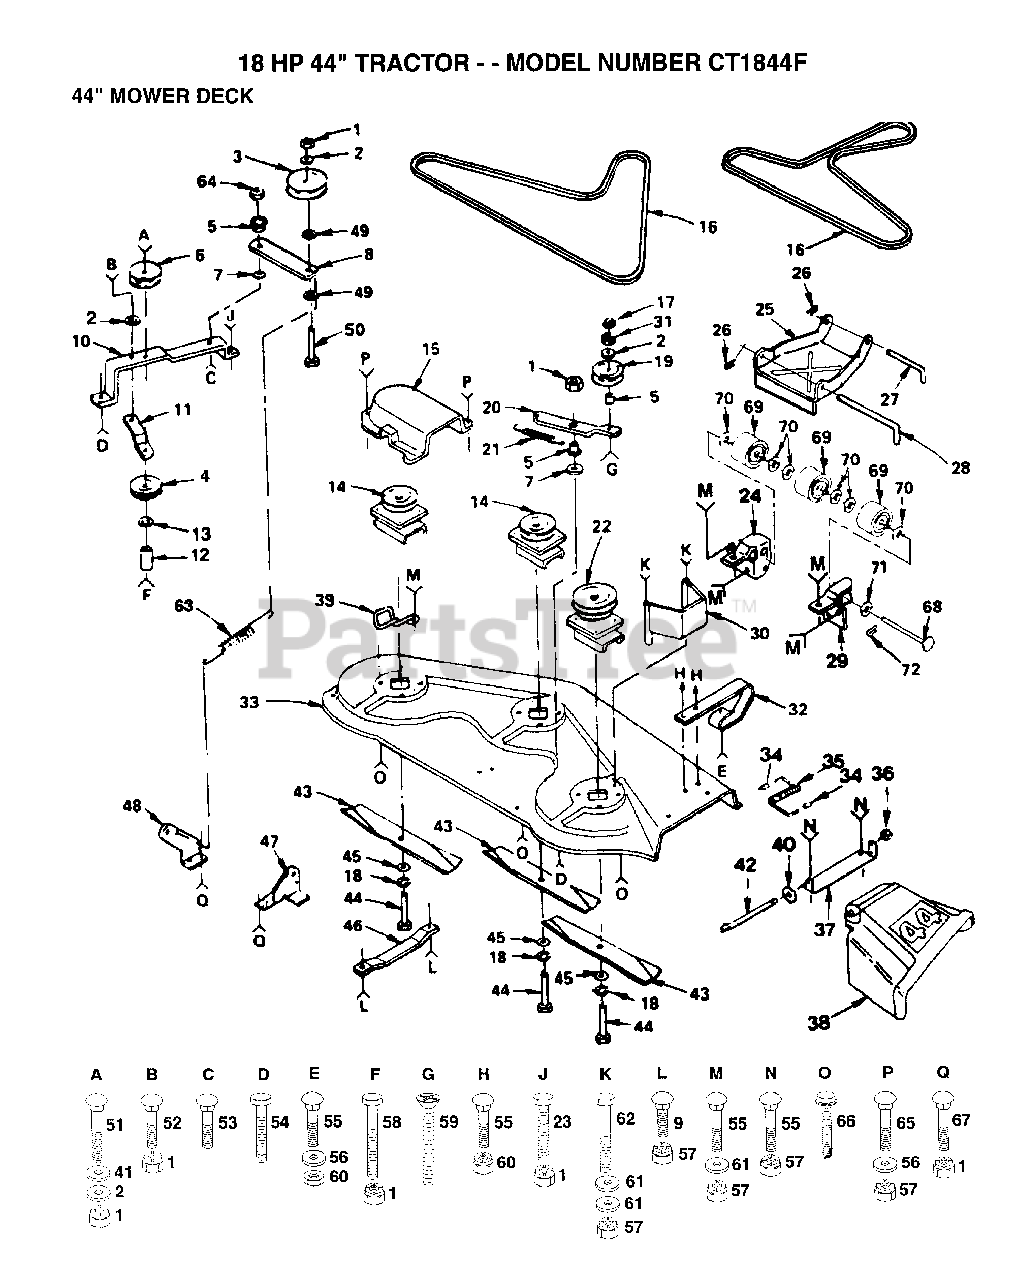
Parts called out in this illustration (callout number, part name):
2	WASHER
3	PULLEY IDLER
4	IDLER-FLAT T
5	SPACER RETAINER
6	IDLER-INSIDE T
7	"WASHER, WEAR LT"
8	ARM IDLER
9	BOLT
10	"SUPPORT YT, BAR"
11	BRACE-IDLER YT
12	SPACER
13	WASHER
15	GUARD YT
16	BELT-V.79.1.MWR
17	NUT.HEX.3/8-16UNC
19	"WASHER, PLAIN LT"
20	ARM-IDLER YT
22	JACKSHAFT
23	BOLT
24	BRACKET LH YTH
25	LINK.PARALLEL
26	SPRING.RETAINER
27	"ROD, FRT. PARAL T"
28	HINGE PIN T
29	BRACKET RH YTH
30	GUARD BELT HYT
31	LOCKWASHER
32	RUNNER.RH
34	CAP-SLEEVE LT
35	SPRING TORSION
36	NUT PUSH M
37	BRKT DEFLECTOR
38	DEFLECTOR SHIELD
39	BELT RETIANER
40	WASHER
41	WASHER
42	ROD-HINGE T
44	BOLT.3/8-24X1-1/2
45	WASHER
46	RUNNER-LH M
47	BRKT SUSP REAR RH
48	BRKT SUSP REAR LH
49	WASHER
50	BOLT
51	BOLT
53	BOLT
55	BOLT
56	WASHER
58	BOLT - HEX 3/8 - 16 X 3
59	SCREW YT
61	WASHER M
62	BOLT
63	"SPRING.EXT.8.5"""
64	LOCKNUT
66	SCREW
67	BOLT
68	PIVOT PIN T
69	ROLLER T
70	WASHER T
72	COTTER PIN
